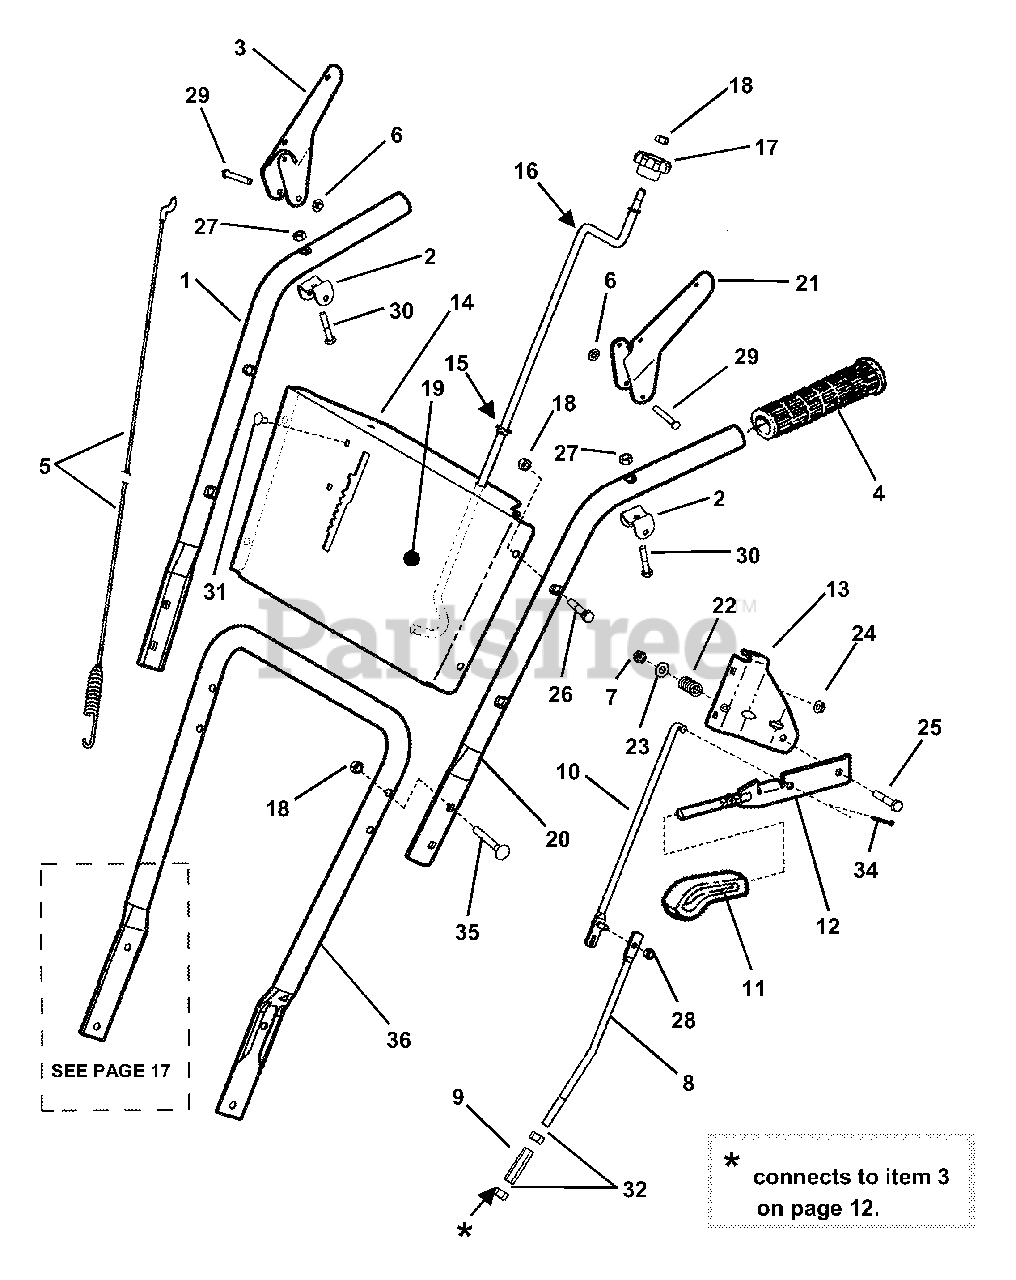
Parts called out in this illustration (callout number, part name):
1	BAR, Right Side Handle
2	BRACKET, Handle
3	HANDLE, Right Side
4	GRIP, Handle
5	CABLE, Clutch
6	NUT, 1/4" Push
7	NUT, 5/16-24 Hex Center Lock, Grade B
8	ROD, Lower Shift
9	CONNECTOR (3/8-16 thread)
10	ROD, Upper Shift
11	KNOB, Shift Handle
12	HANDLE, Shift (weldment)
13	BRACKET, Shift Lever
14	PANEL, Control
15	BUSHING
16	CRANK, Chute
17	KNOB, Chute Crank
18	NUT, 5/16-18 Hex Center Lock, Grade B
19	DECAL, Control- 8/24
20	BAR, Left Side Handle
21	HANDLE, Left Side
22	SPRING, Shift Lever
23	WASHER, 5/16 Flat
24	NUT, 1/4-20 Hex Flange Lock
25	SCREW, 5/16-24 x 1-3/4" Hex Head Cap, Grade 2
26	SCREW, 5/16-18 x 1-1/2" Hex Head Cap, Grade 5
27	NUT, 1/4-28 Hex Top Lock
28	NUT, 1/4-20 Hex Nyloc
29	PIN, 1/4 x 1-7/8" Clevis
30	SCREW, 1/4-28 x 1-3/8" Hex Head Cap, Grade 5
31	BOLT, 1/4-20 x 1/2" Short Neck Carriage, Grade 5
32	NUT, 3/8-16 Hex, Grade B
34	PIN, 1/8 x 1" Cotter
35	BOLT, 5/16-18 x 2", Square Neck Carriage, Grade 5
36	HANDLE BAR, Lower
